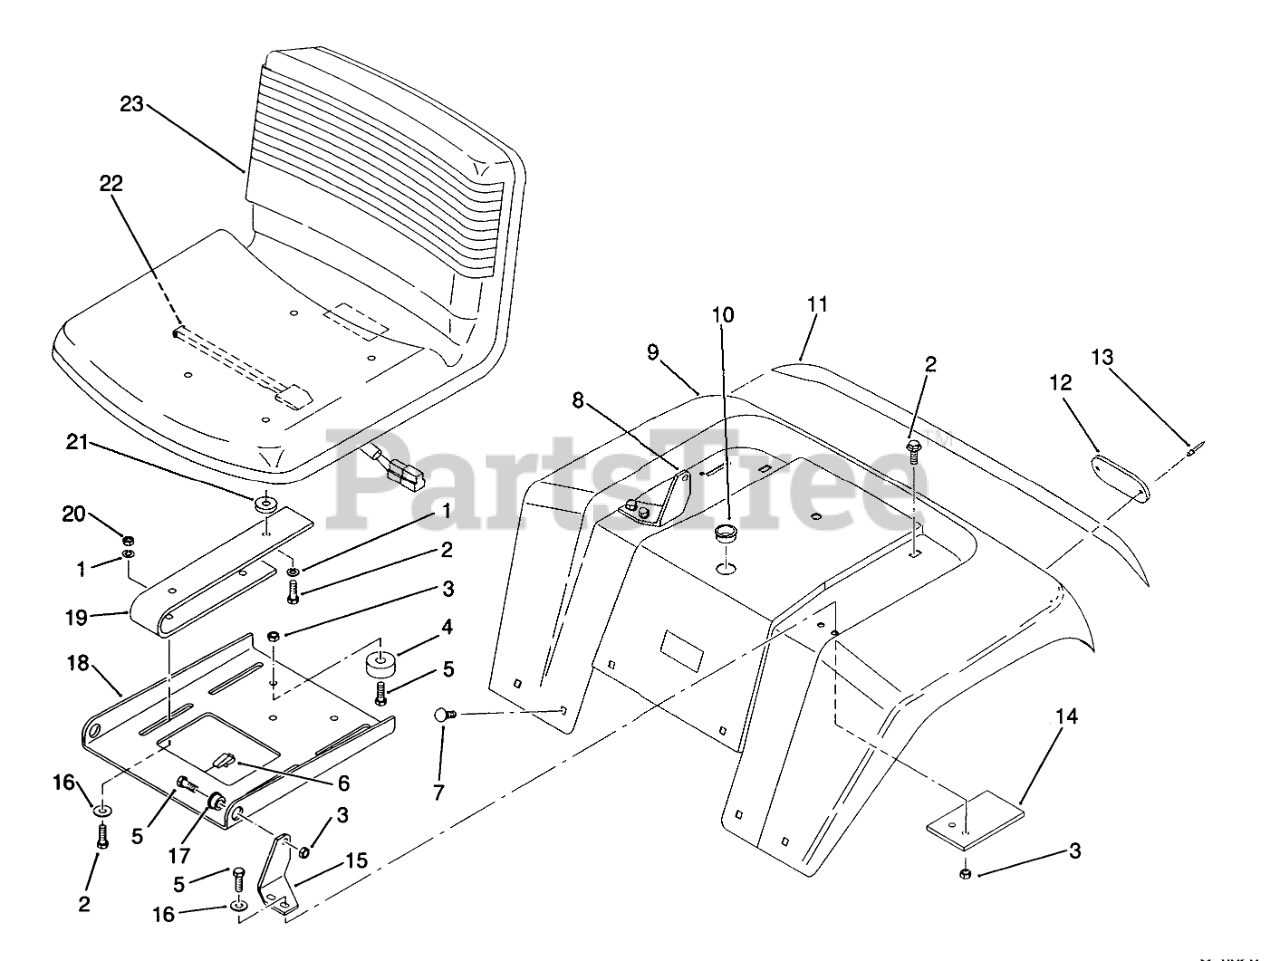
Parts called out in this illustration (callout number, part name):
1	Washer-Lock
2	Screw-Cap, Hex. Hd.
3	Nut
4	BUMPER
5	Screw-Cap Hex. Hd.
6	J-CLIP
7	Bolt-Carriage
8	Bracket-Pivot RH
9	FENDER R
10	BUSHING-NYLON 1.093
11	DECAL-FENDER
12	Reflector
13	Poprivet
14	PLATE R
15	BRACKET-PIVOT L.H B
16	Washer
17	BUSHING
18	PLATE-SEAT PIVOT B
19	SPRING-SEAT B
20	Nut
21	SPACER-NYLON
22	SWITCH-SEAT
23	SEAT V-410
